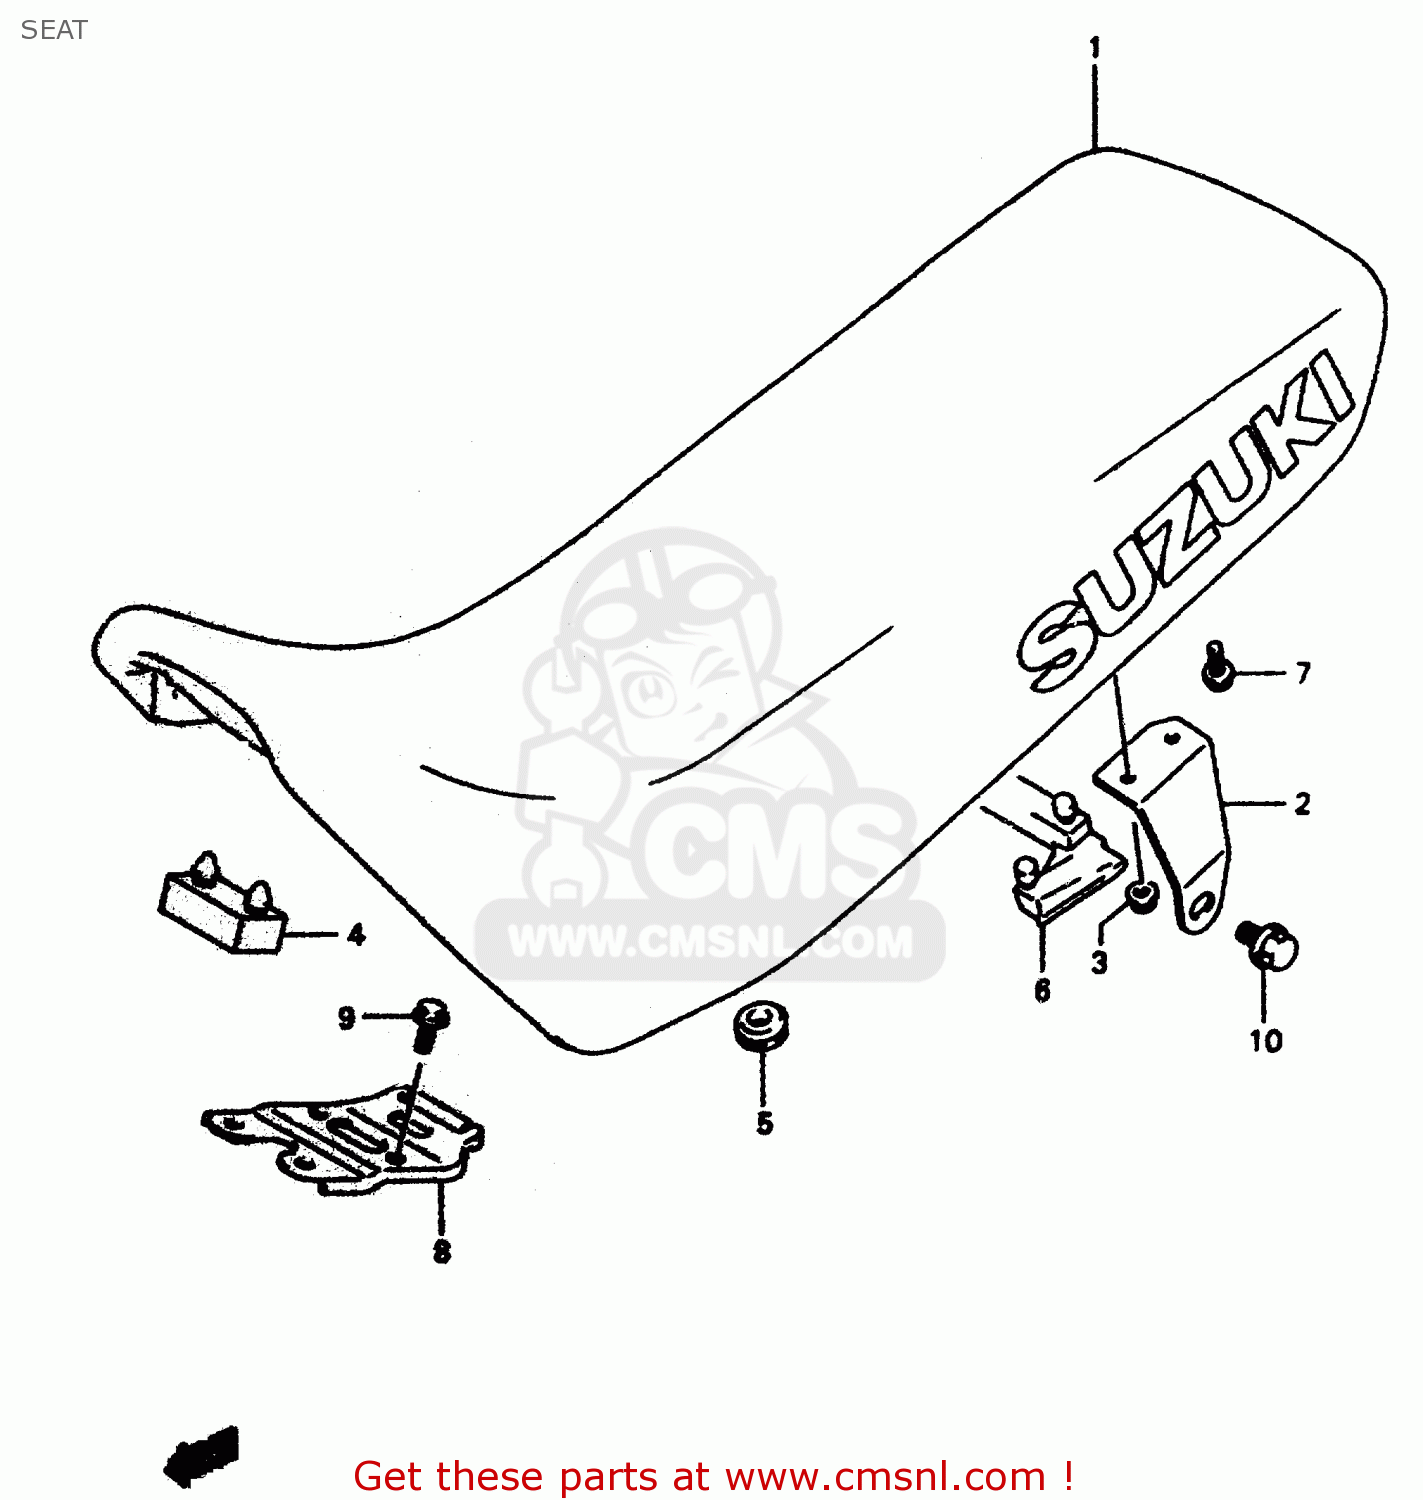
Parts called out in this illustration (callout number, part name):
1	SEAT SET
2	BRACKET,SEAT,R
3	NUT
4	CUSHION
5	CUSHION
6	CUSHION
7	BOLT
8	PLATE,SEAT FR HOOK
9	BOLT
10	BOLT
